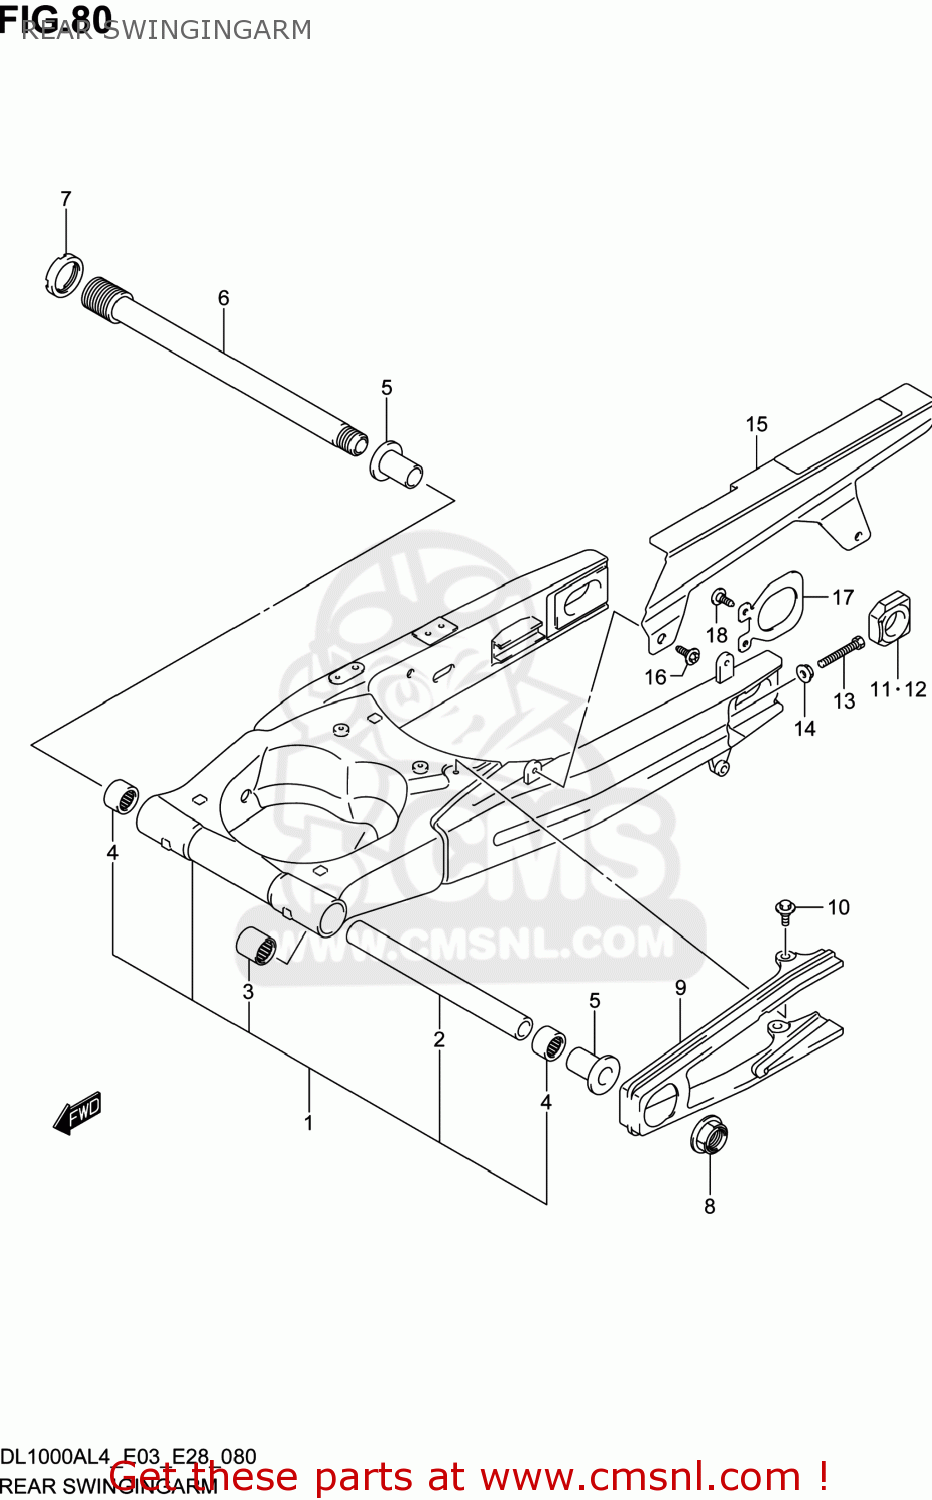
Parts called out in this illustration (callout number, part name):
1	SWINGINGARM ASSY,REAR
2	SPACER,RR SWGARM PIVOT CTR
3	BEARING(20X27X30)
4	BEARING(27X35X35)
5	SPACER,RR SWGARM PIVOT BEARING
6	SHAFT,RR SWGARM PIVOT
7	NUT,RR SWGARM PIVOT BOLT
8	NUT
9	BUFFER,CHAIN TOUCH DEFENSE
10	BOLT(6X17.8)
11	ADJUSTER,CHAIN
12	ADJUSTER,CHAIN
13	BOLT(8X50)
14	NUT
15	CASE,CHAIN
16	BOLT(6X12)
17	PLATE,RR SWING ARM BRKT
18	SCREW(6X12)
